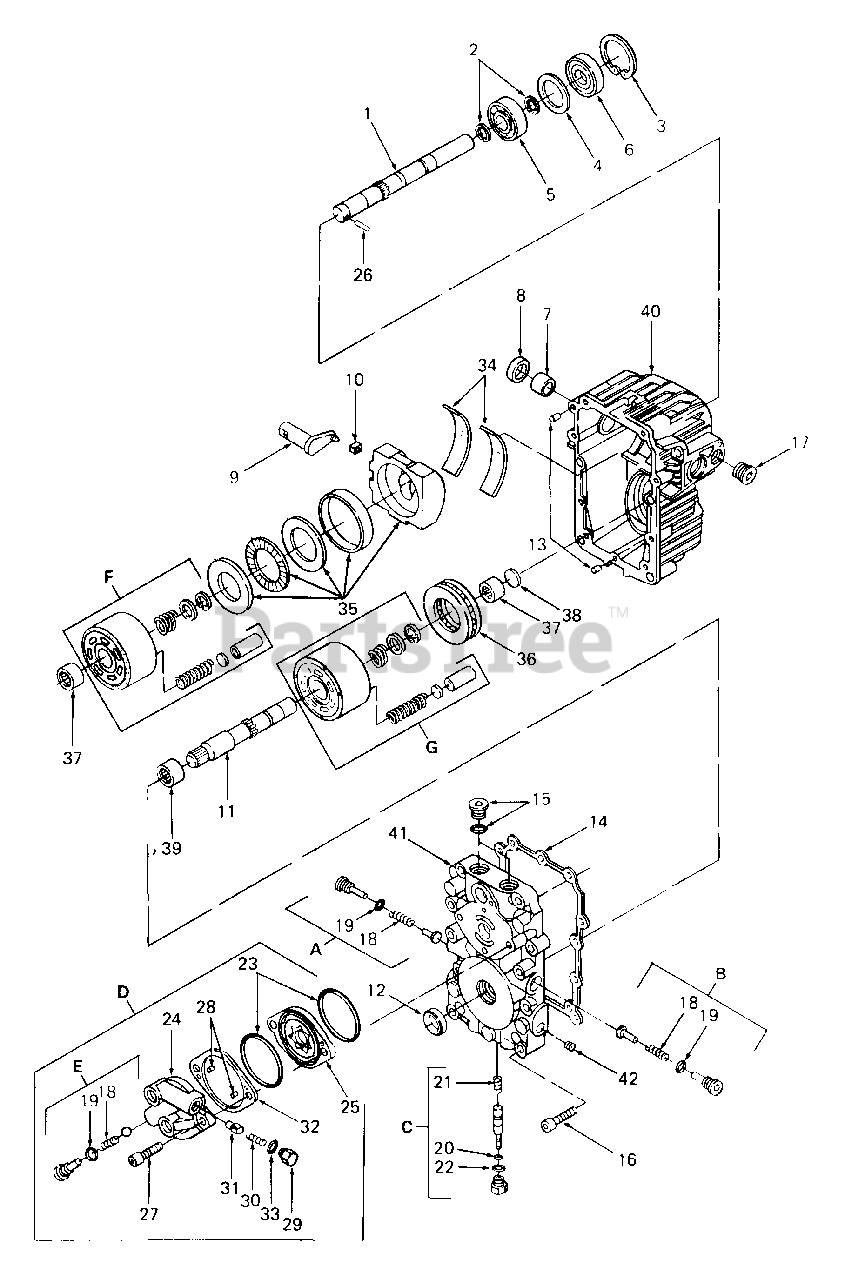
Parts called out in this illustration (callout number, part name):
1	Shaft
2	Ring, Retaining
3	Ring, Retaining
4	Spacer
5	Bearing, Ball
6	Seal, Lip
7	Bearing, Journal
8	Seal, Lip
9	Arm, Trunnion
10	Guide, Slot
11	Shaft, Motor
12	Not used in this application
14	Gasket, Center Section
19	O-Ring
20	O-Ring
21	Spring
22	O-Ring
23	O-Ring
24	Housing, Charge Pump
25	Gerotor Assy
29	Plug
31	Cone, Relief Valve
32	Shim, Charge Pump
34	Bearing, Cradle
35	Swashplate Assy
36	Bearing, Ball Thrust
37	Bearing, Needle
38	Washer, Thrust
39	Bearing, Needle
40	Housing Assy
41	Center Section Assy
A	Kit, Poppet Check Valve
B	Kit, Orificed Check Valve
C	Kit, Bypass Valve
D	Kit, Charge Pump
E	Kit, Check Valve
F	Kit, Pump Cylinder Block
G	Kit, Motor Cylinder Block
